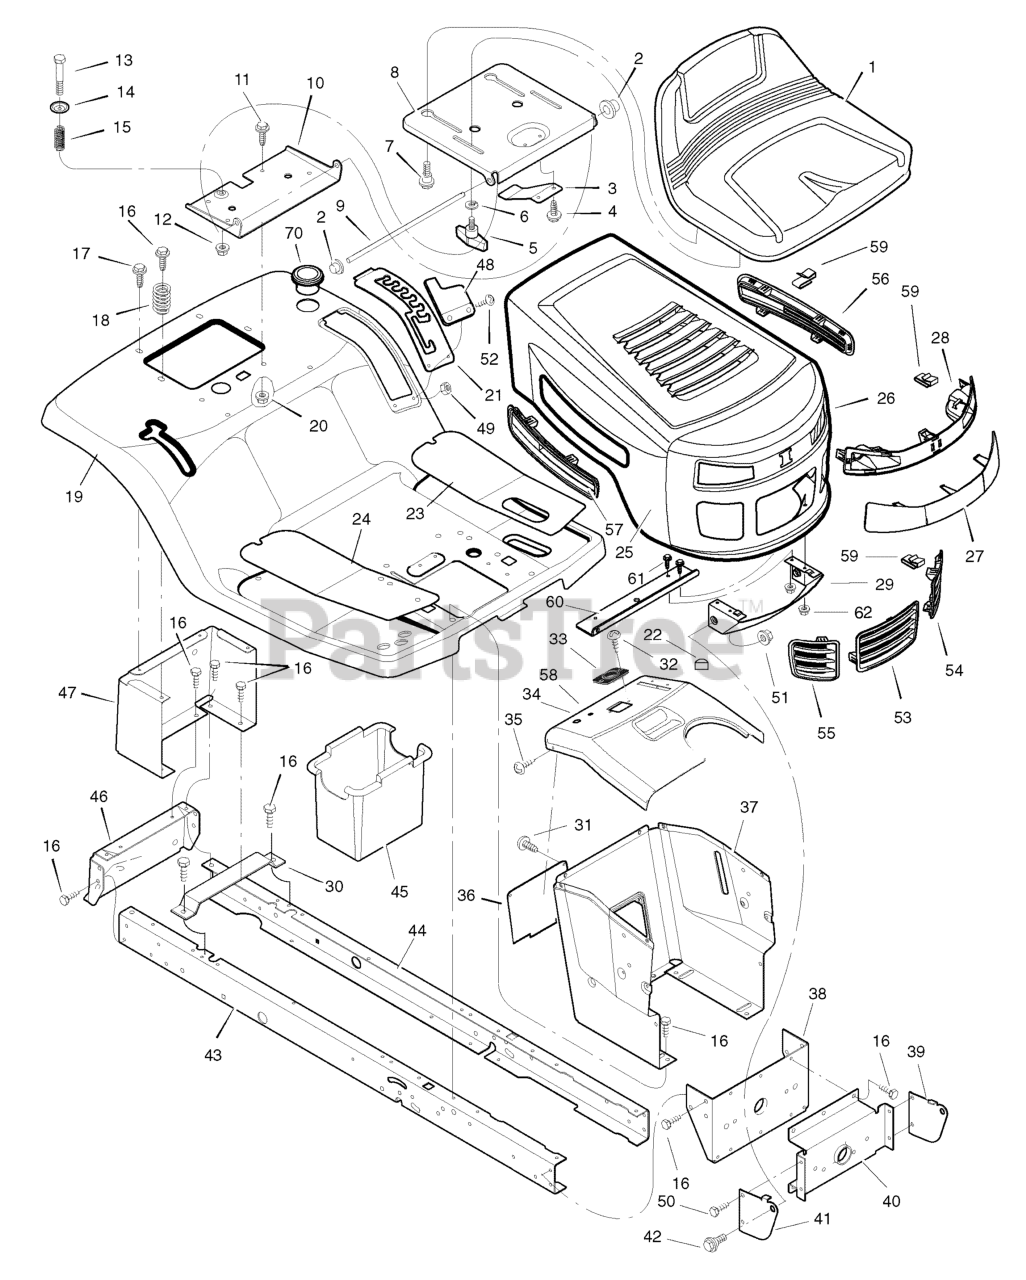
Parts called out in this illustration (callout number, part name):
1	Seat
2	Cap, Push On
5	Bolt, Wing
6	Washer
7	Bolt, Shoulder
8	Support, Seat
9	Rod, Pivot
10	Bracket, Pivot
11	Bolt
13	Bolt, Shoulder
20	Nut
21	Plate, Index Detent
22	Bumper, Black
23	Mat, Left
24	Mat, Right
26	Grille
27	Lens, Plastic Cover
28	Assembly, Headlamp
29	Bracket, Lower Pivot
30	Support, Battery
33	Bearing, Steering
34	Dash
36	Panel, Access
37	Support, Dash
38	Bracket, Rear Hanger
39	Support, Left Grille
40	Axle, Hanger
41	Support, Right Grille
42	Bolt, Shoulder
43	Frame, Right
44	Frame, Left
45	Container, Battery
46	Plate, Hitch
47	Panel, Rear
48	Cover, Detent
53	Insert, Grille Center
54	Insert, Left Grille
55	Insert, Right Grille
56	Insert, Hood Left
57	Insert, Hood Right
58	Grommet, Parking Brake
59	Fastener, S-Clip
60	Bracket, Support
61	Screw, Hex
62	Nut
70	Holder, Cup
